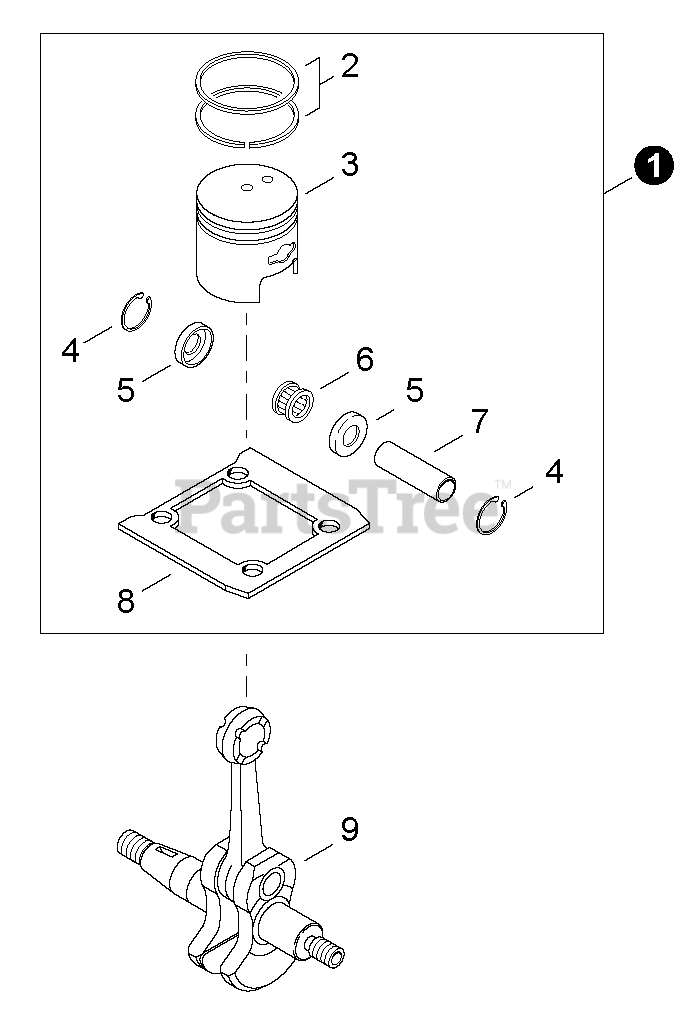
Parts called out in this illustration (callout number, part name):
1	PISTON KIT
2	RING, PISTON
3	PISTON
4	RING, RETAINING
5	WASHER, THRUST
6	BEARING, NEEDLE - 11
7	PIN, PISTON
8	GASKET, CYLINDER
9	CRANKSHAFT ASSY
